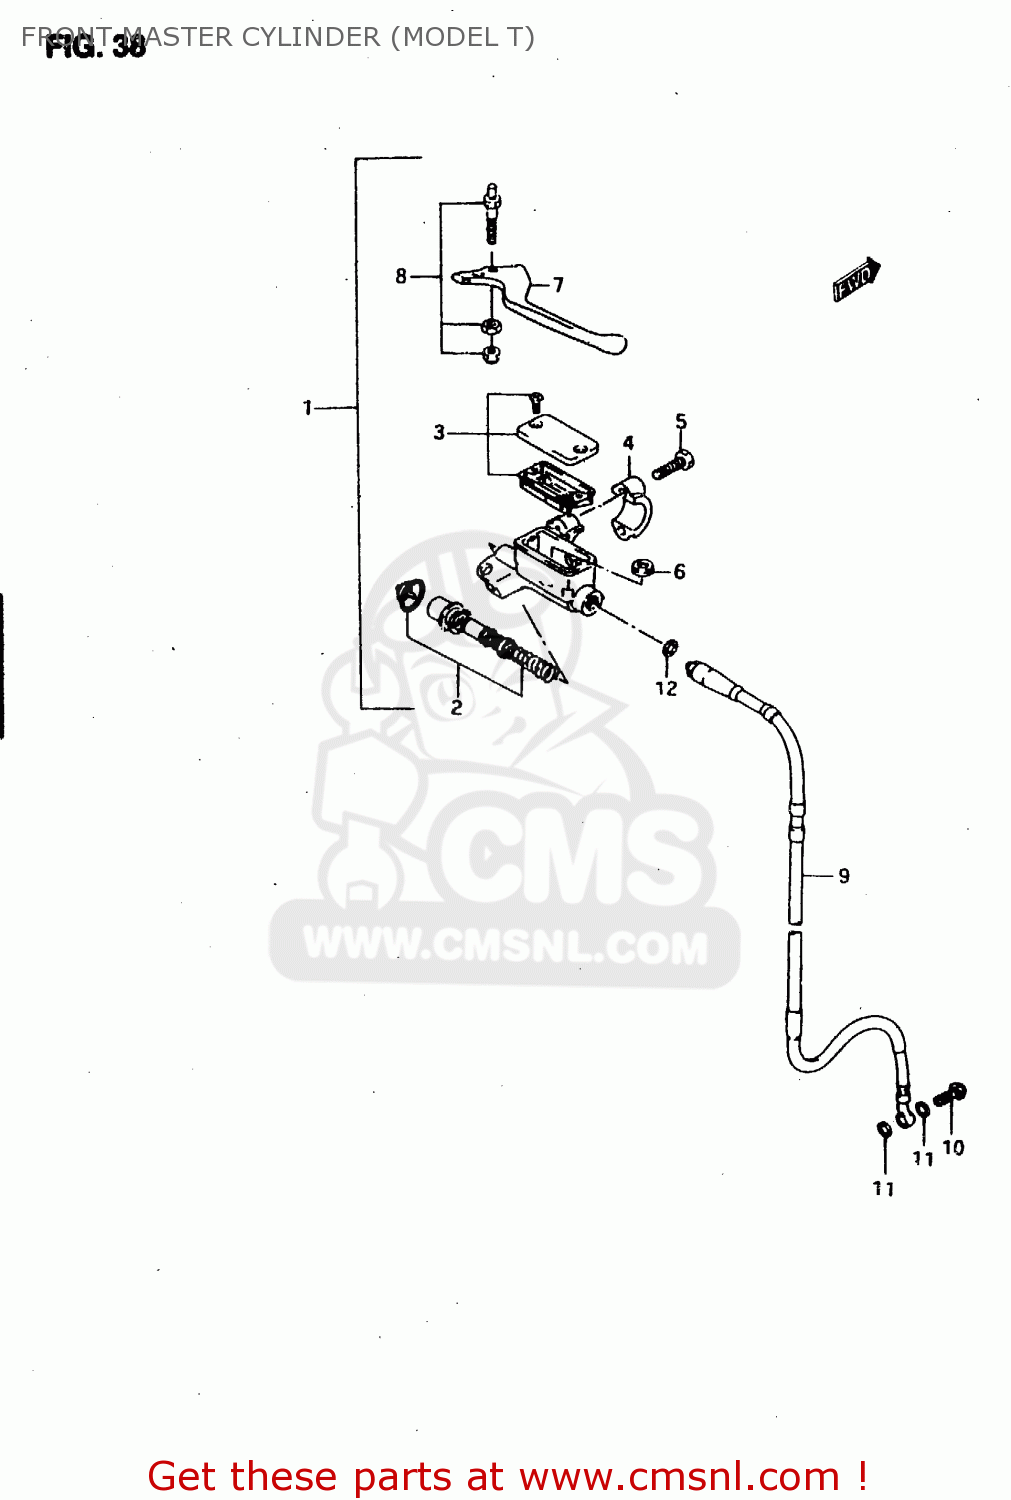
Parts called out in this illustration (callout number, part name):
1	CYLINDER ASSY, FRONT MASTER
2	PISTON&CUP SET
3	CAP SET
4	HOLDER
5	BOLT
6	PROTECTOR
7	LEVER, BRAKE
8	SCREW SET
9	HOSE, FRONT BRAKE
10	BOLT
11	WASHER
12	WASHER
